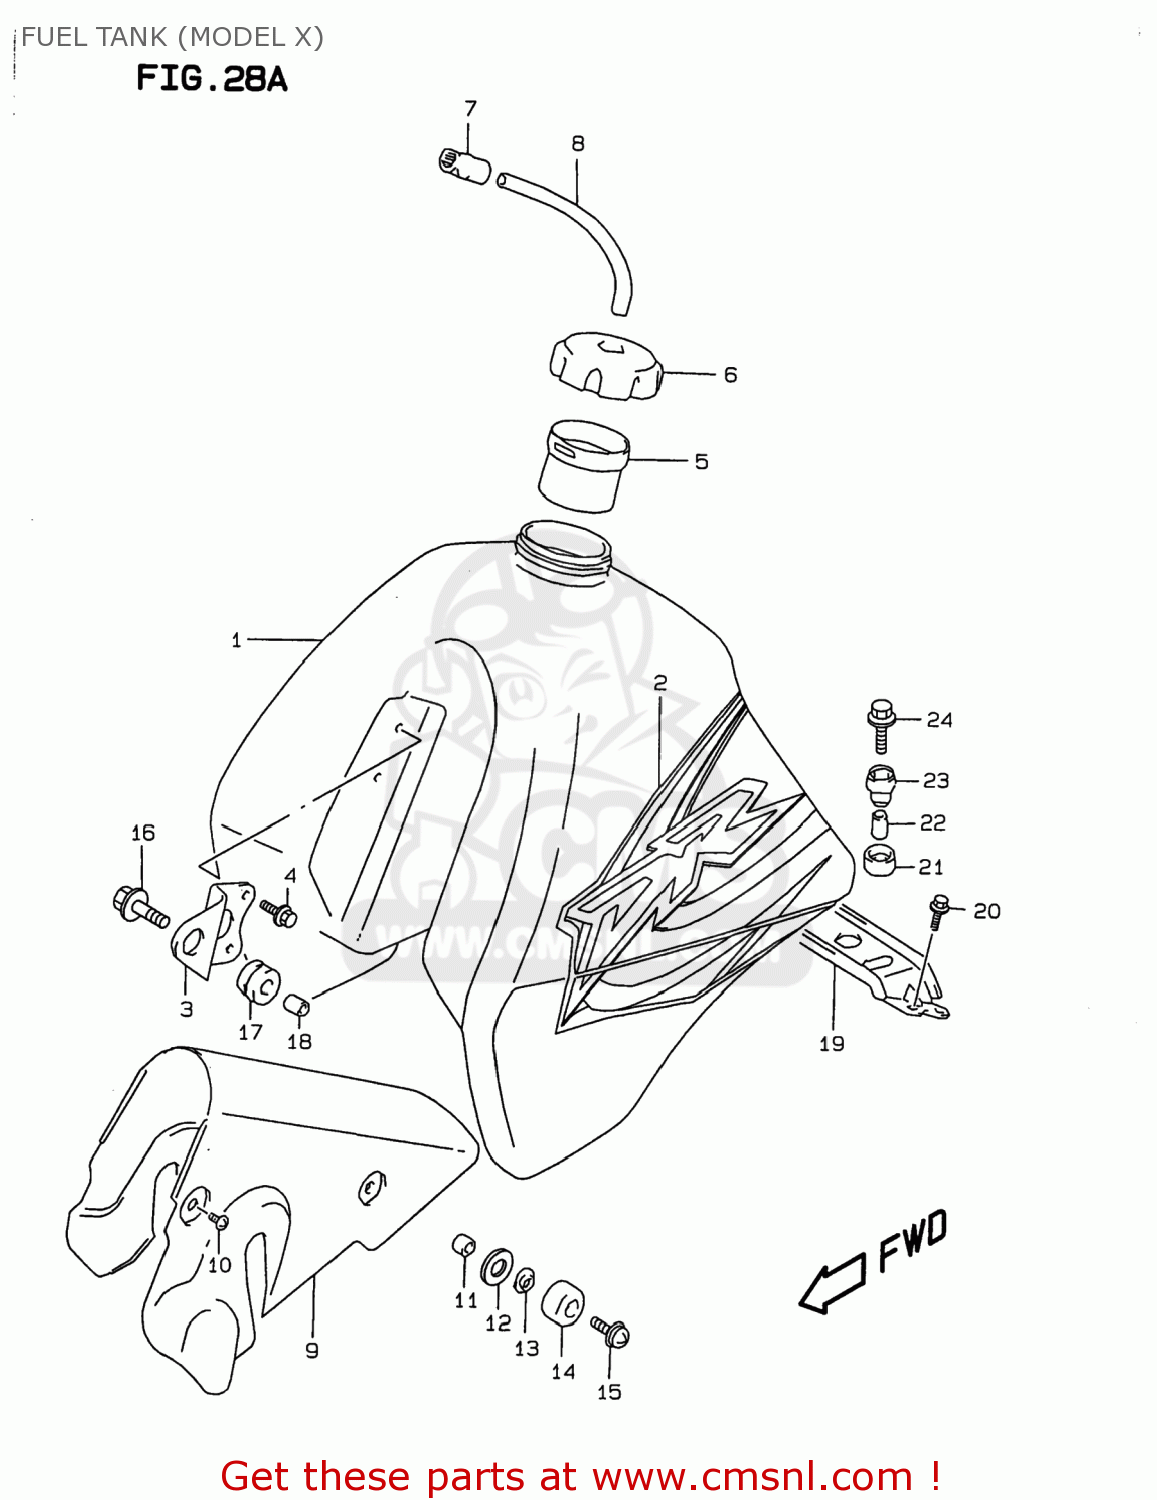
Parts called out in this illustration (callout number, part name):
1	TANK ASSEMBLY,FUEL
2	TAPE SET,FUEL TANK
3	BRACKET,FUEL TANK,FRONT
4	BOLT
5	TUBE,FILLER INLET
6	CAP ASSY,FUEL TANK
7	CLAMP,BREATHER HOSE
8	HOSE(5X8.2X600)
9	HEAT SHIELD,FUEL TANK
10	BOLT
11	SPACER(6.1X14X7.2)
12	WASHER(6.5X26X2.3)
13	WASHER
14	CUSHION
15	SCREW
16	BOLT
17	CUSHION
18	SPACER(8.5X12X12.5)
19	BRACKET,FUEL TANK RR
20	BOLT
21	CUSHION
22	SPACER(6.5X9X18)
23	CUSHION
24	BOLT(6X30)
